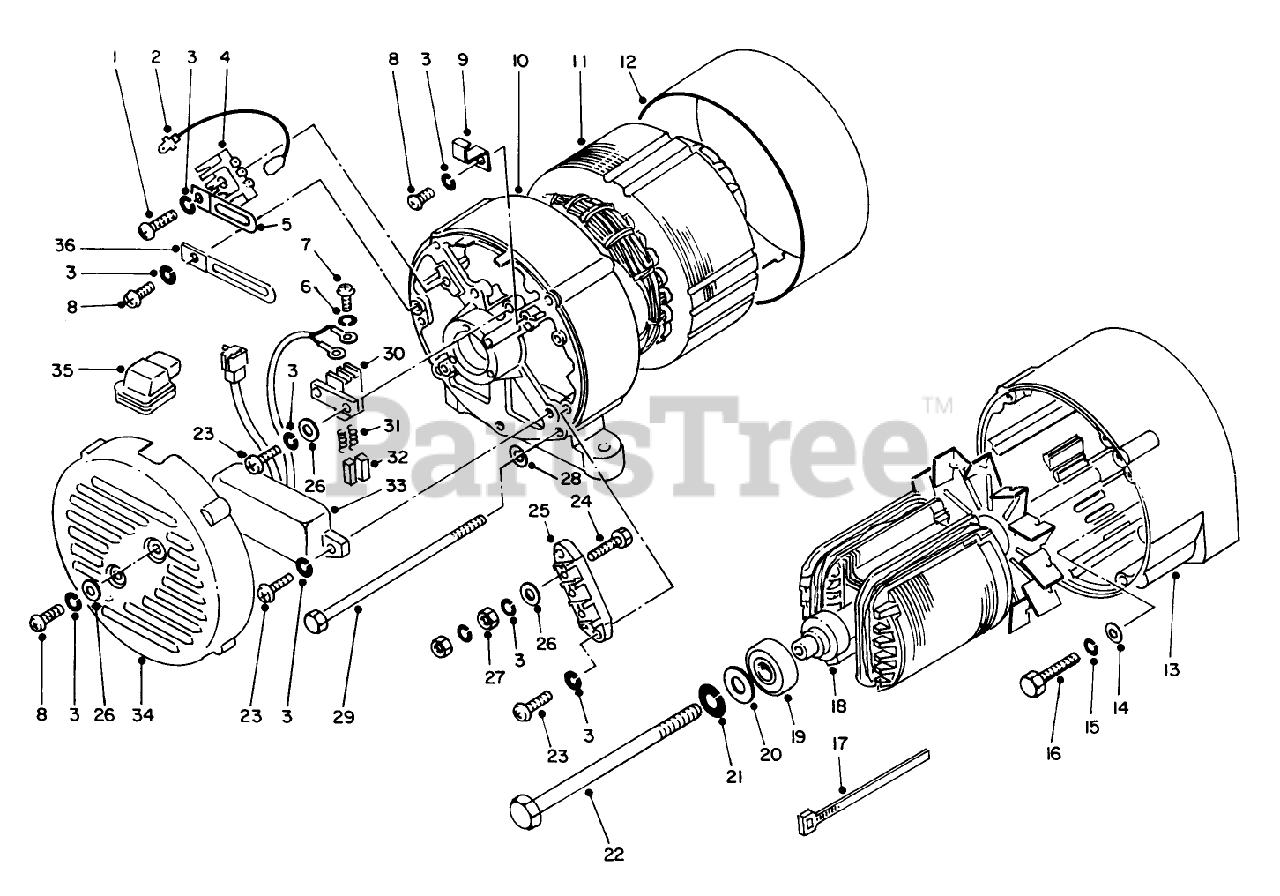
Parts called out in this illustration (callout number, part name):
15	WASHER-LOCK
28	LOCKWASHER
32	BRUSH
